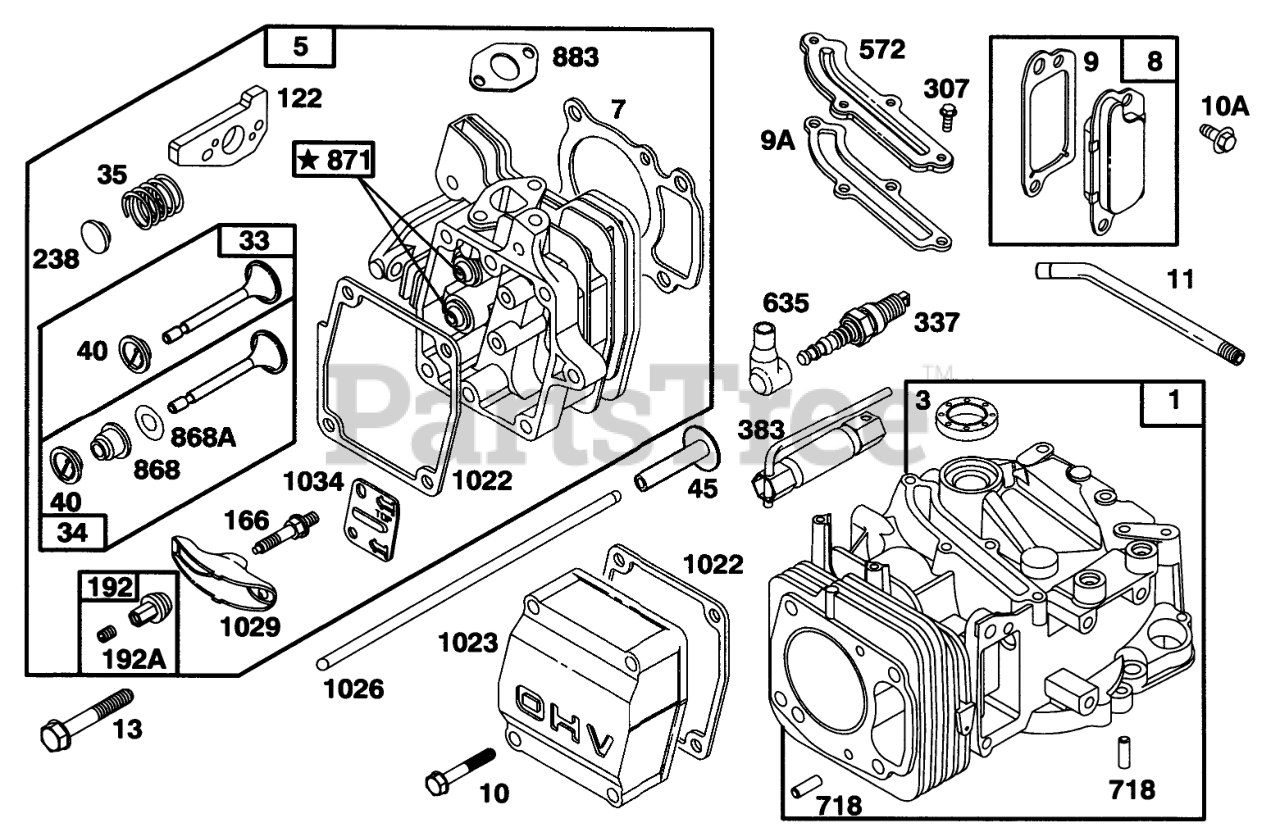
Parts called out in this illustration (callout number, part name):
1	CYLINDER ASSEMBLY
3	SEAL - OIL
5	CYLINDER HEAD
7	CYLINDER HEAD GASKET
8	Breather Assy
9	BREATHER GASKET
9A	GASKET-BREATHER
10	HEX HEAD SCREW
10A	HEX HEAD SCREW
11	TUBE - BREATHER
13	SCREW - CYLINDER HEAD
33	EXHAUST VALVE
34	INTAKE VALVE
35	VALVE SPRING
40	SPRING RETAINER
45	VALVE TAPPET
122	ADAPTER ASSEMBLY
166	ROCKER ARM STUD
192	NUT - HEX SPECIAL
192A	SCREW SET
238	VALVE CAP
307	SCREW - SEM
337	PLUG-SPARK
383	WRENCH-SPARK PLUG
572	BAFFLE - CYCLINDER
635	SPARK PLUG ELBOW
718	DOWEL - SLEEVE
868	ASM - VALVE SEAL
868A	Seal-Valve
871	Bushing-Guide
883	EXHAUST GASKET
1022	ROCKER COVER GASKET
1023	COVER - VALVE
1026	PUSH ROD
1029	ROCKER ARM
1034	PUSH ROD GUIDE
